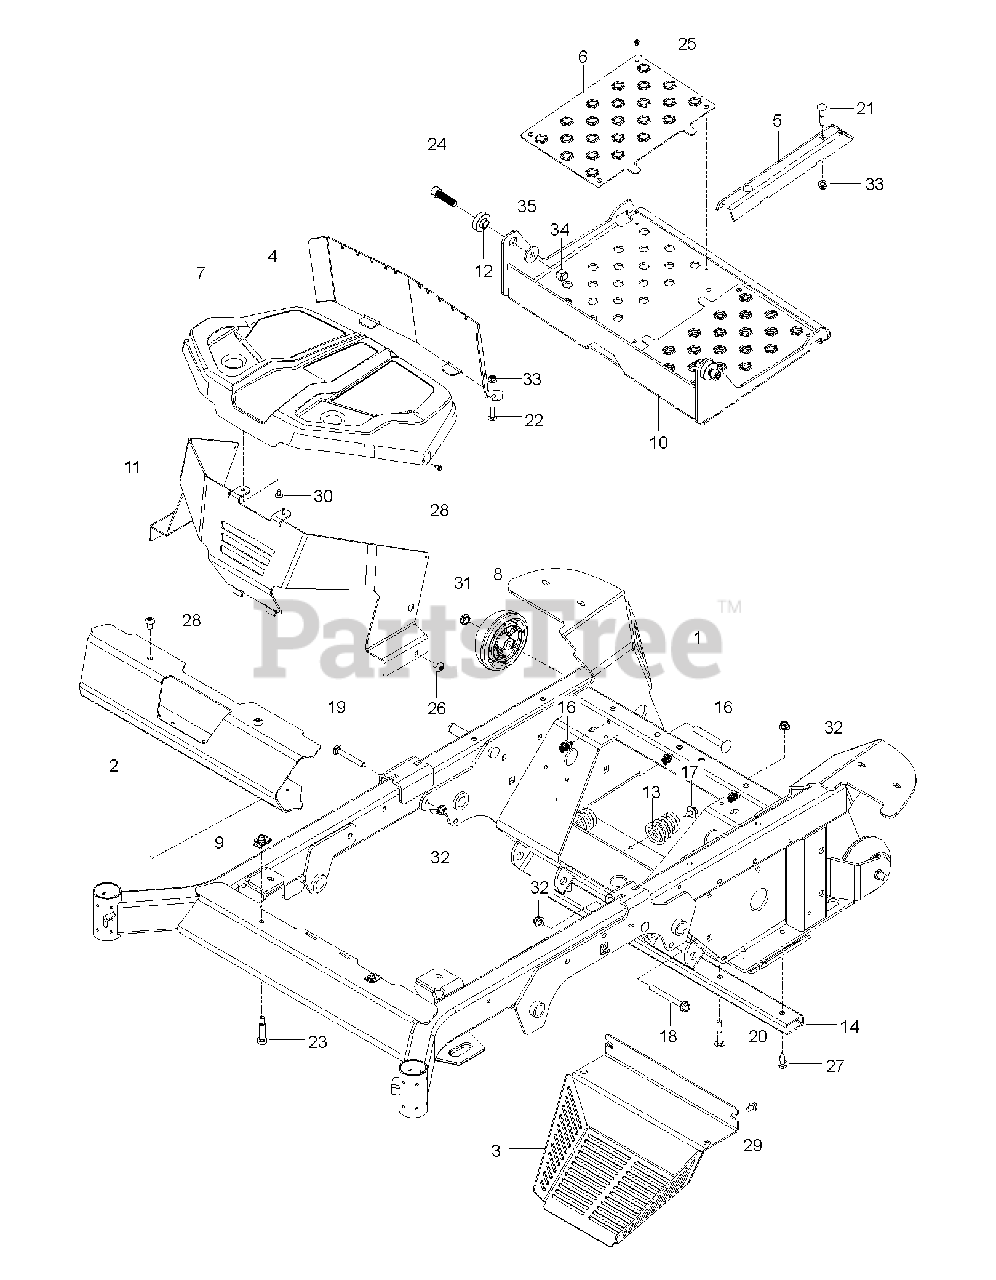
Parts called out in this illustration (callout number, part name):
1	CHASSIS.WELDMENT.VZ.MS668
2	COVER FRONT CROSSMEMBER VZ
3	COVER PTO VZ MS668 ORANGE
4	BAFFLE PLATE PUMP X431 E-COAT
5	BRACKET ANGLE OPERATOR STAND V
6	FOOTPLATE OPERATOR STAND VZ MS
7	SHROUD PUMP
8	Gage Wheel, Rally Narrow
9	SCREW.BUTTON.HEAD.TORX.3/8-161
10	PLATE OPERATOR STAND VZ MS498
11	PUMP SHROUD
12	SPACER.IDLER.METAL.POWDER
13	SPRING.COMPRESS.SEAT.
14	TUBE SKIDPLATE
15	CABLE, 1/4 BLACK FIR TREE
16	Bolt, 1/2 - 13 X 3.5 Carriage
17	BOLT, 5/16-18 X 1 3/4
18	HHFS 3/8-16 X 3.5 GD 5 ZD
19	3/8-16 X 3` CARR BOLT
20	BOLT CARRIAGE
21	Carriage Bolt
23	BOLT HEXAGON SOCKET HEAD, SHOU
24	Bolt, 1/2-13 X 1.75 Cap
25	SCREW 10-24 X .325 TORX PAN
27	SCREW 3/8-16X1
28	SCREW, HEX HEAD, TAPPING
29	SCR 5/16-18 X 1/2 SELFTAP ZN
30	SCREW.#10 X 0.500
31	NUT 1/2-13 HEX JM NYL
32	NUT 3/8-16 HEX FLG NYLOC ZD
33	5/16-18 NYLOC FLANGE NUT
34	RP NUT 1/2-13 HEX NYLOC ZD
35	WASH USS FLAT 1/2
